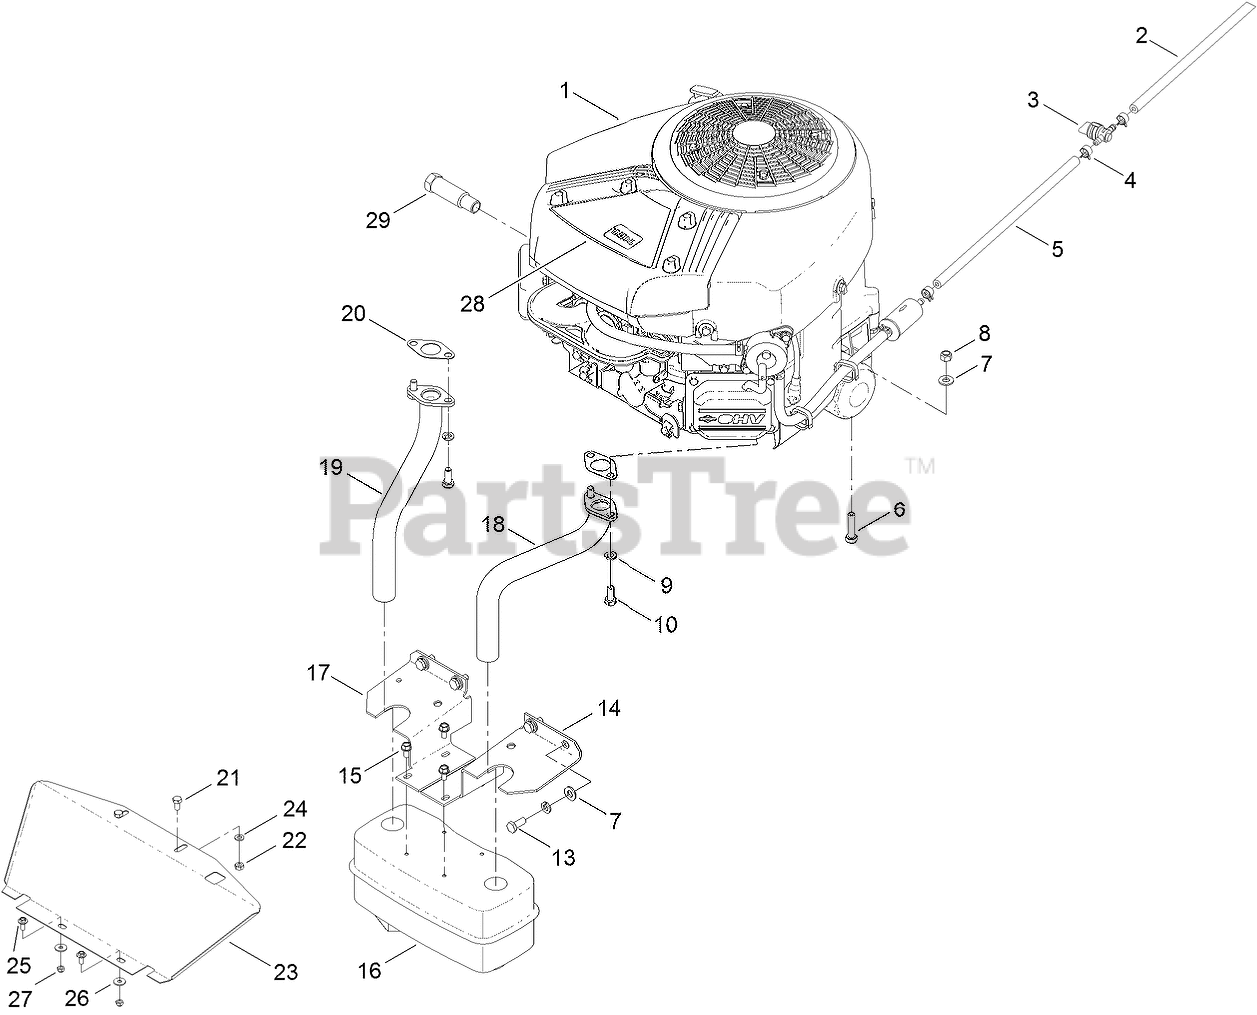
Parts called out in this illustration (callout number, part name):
2	LINE-FUEL
3	VALVE-TANK, FUEL
4	CLAMP-LINE, FUEL
5	LINE-FUEL
6	SCREW-HH
7	WASHER-PLAIN
8	NUT-LOCK, NI
9	WASHER-SPRING
10	SCREW-HH
13	SCREW-HH
14	GUARD-MUFFLER, LH
16	MUFFLER
17	GUARD-MUFFLER, RH
18	TUBE-EXHAUST, LH
19	TUBE-EXHAUST, RH
20	GASKET-EXHAUST
21	SCREW-HH
22	NUT-LOCK
23	SHIELD-HEAT
24	WASHER-FLAT
26	WASHER-FLAT
27	NUT-LOCK
28	DECAL-ENGINE
29	COUPLER-DRAIN, OIL
